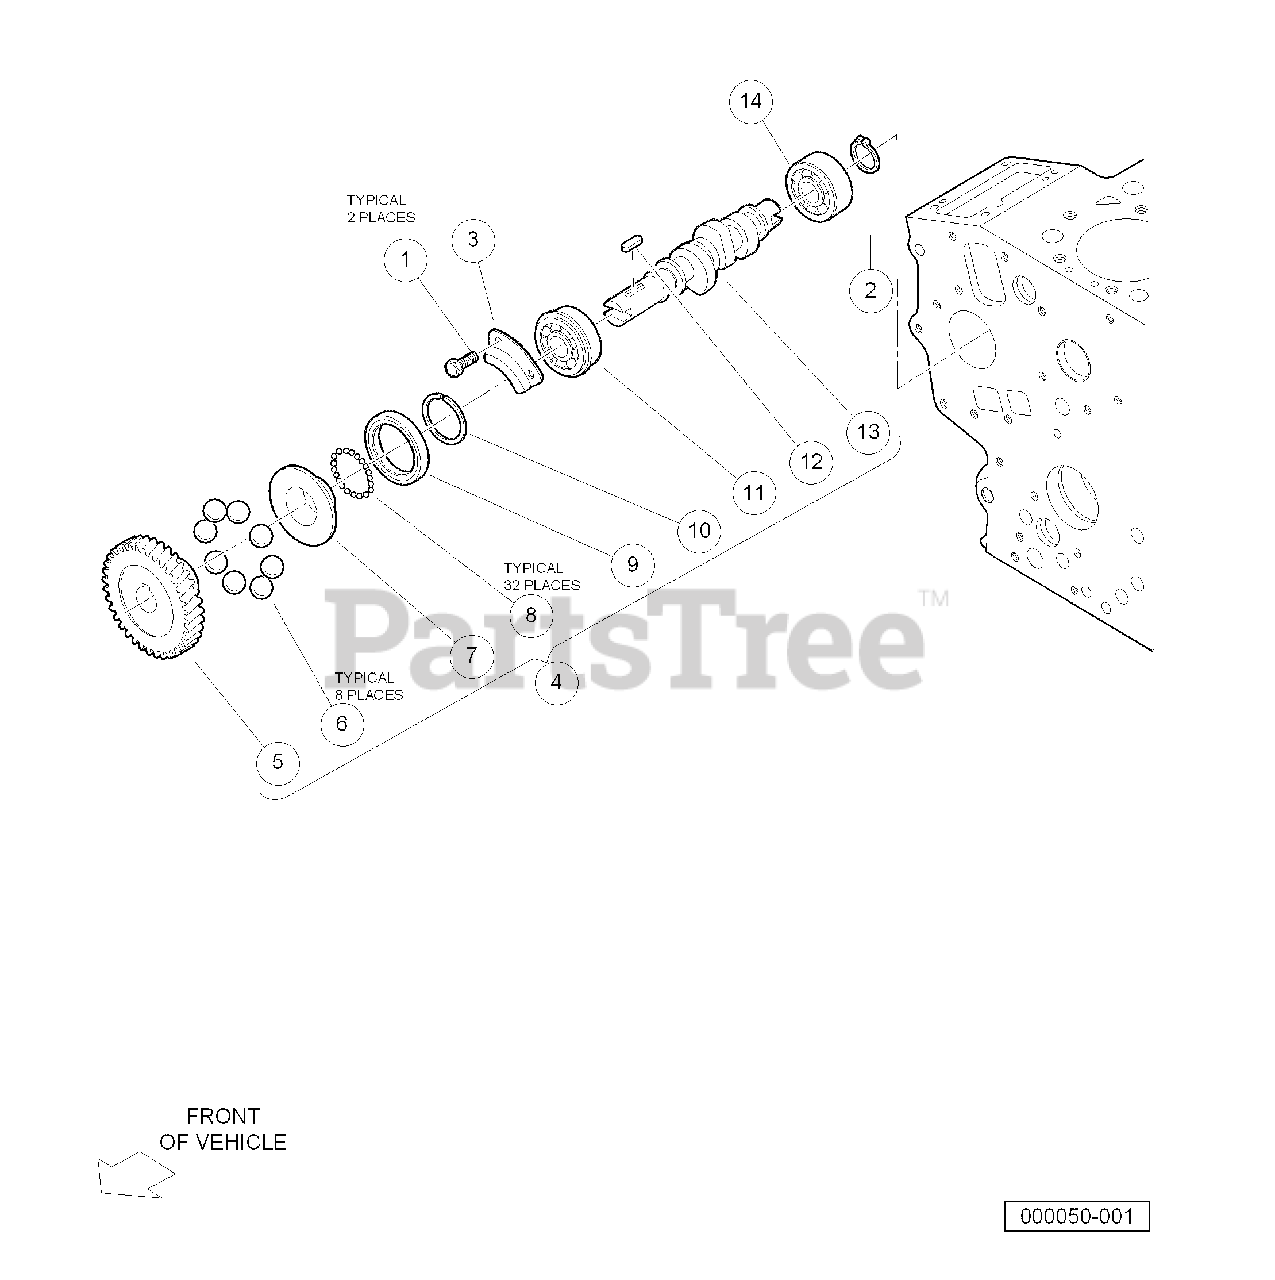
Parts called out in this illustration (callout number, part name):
1	Bolt, D722, Cam End
2	Circlip, External
3	Stopper, Fuel, C/shaft
4	Assy, Fuel Camshaft
5	Gear, Injection Pump
6	Ball, Injection Pump
7	Sleeve, Governor
8	Ball, Governor
9	Case, Governor Ball
11	Bearing, Ball
12	Key, Feather, Short Camshaft
13	Camshaft, Fuel, Short
14	Bearing, Ball
